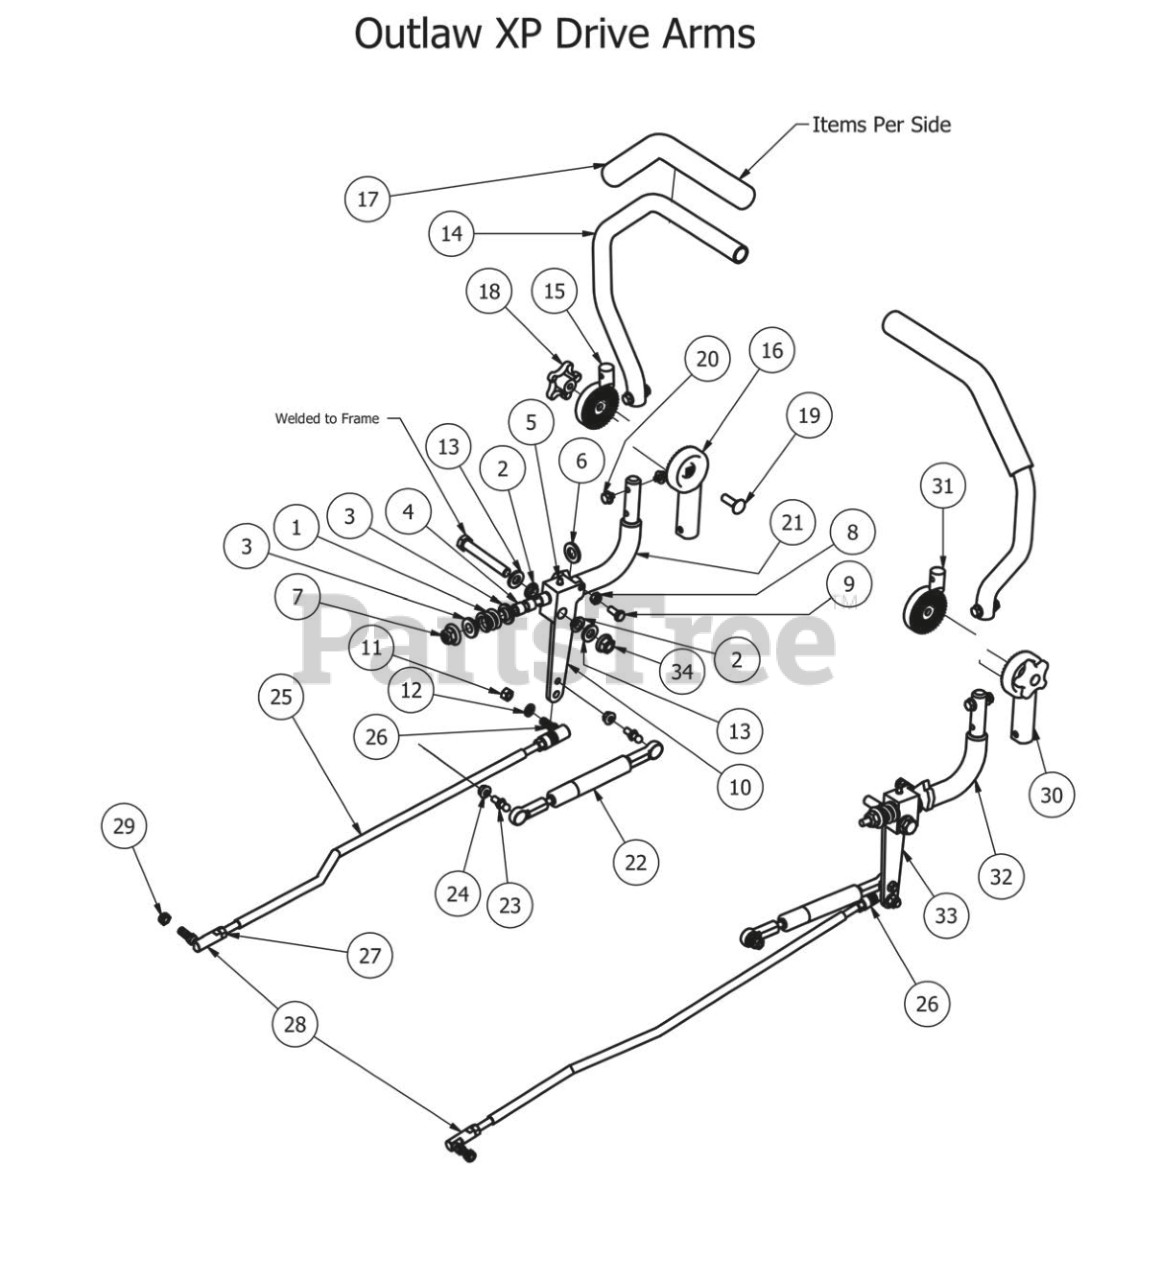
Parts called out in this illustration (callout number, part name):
1	Drive Lever Spring
2	Bushing for 2012 Drive Arms
3	.515 ID Nylon Shoulder Washer
4	.507 ID Nylon Bushing
5	1/4" Drive in Grease Fitting
6	.635 ID Plastic Washer
7	1/2-13 Nylon Flange Nut-Orange
9	5/16" x 3/4" Hex Bolt
10	Drive Arm Lever Housing (Left)
11	3/8" Fine Threaded Jam Nut
12	3/8" Lock Washer
13	.505x1x.125 Oil Impregnated washer
14	Upper Tube-Adjustable Steering
15	Upper adjuster-Steering Arm- Left
16	Lower Adjuster - Steering Arm- Left
17	Black Steering Grip
18	Black Knob for Adjustable Steering Arm
19	3/8" x 1 1/4" Carriage Bolt
20	5/16-18 1/2 HWH Bolt-Steering
21	Steering Arm Elbow - Left
22	Steering Damper for Outlaw
23	10mm Damper Ball Stud-Steering
24	5/16" Flange Nut
25	outlaw XP Push Rod
26	Quick Release Ball Joint
27	3/8" Fine Threaded Jam Nut
28	3/8-24 Ball Joint
29	3/8-24 Nylon Insert jam locknut
30	Lower Adjuster - Steering Arm- Right
31	Upper Adjust Steering Arm- Right
32	Steering Arm Elbow - Right
33	Drive Arm Lever Housing Right
34	1/2-13 Hex Flange (GR.G) ZC
